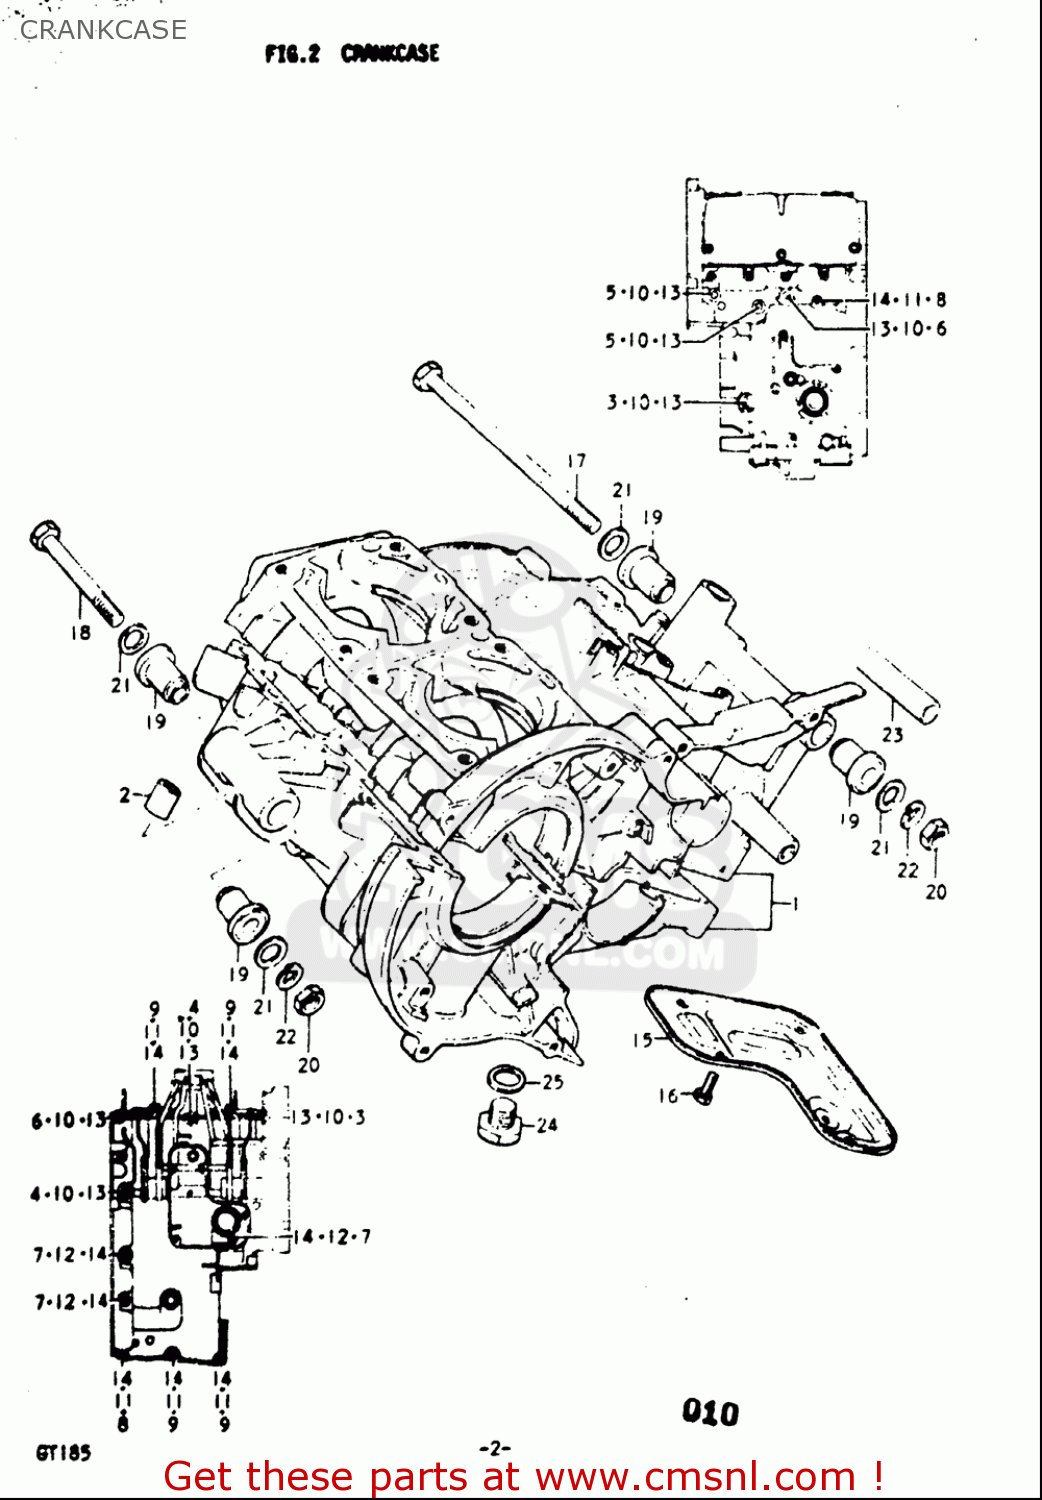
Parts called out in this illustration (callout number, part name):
2	PIN
3	BOLT
4	BOLT
5	BOLT
6	BOLT
7	BOLT
8	BOLT 6X45
9	BOLT(6X35)
10	WASHER
11	WASHER
12	GASKET(6.2X11X1).2 (NAS)
13	WASHER,LOCK
14	WASHER,LOCK
16	BOLT
18	BOLT
20	NUT
21	WASHER
22	WASHER,LOCK
24	PLUG(MAGNETO)
25	GASKET(14X19.2X2) (NAS)
